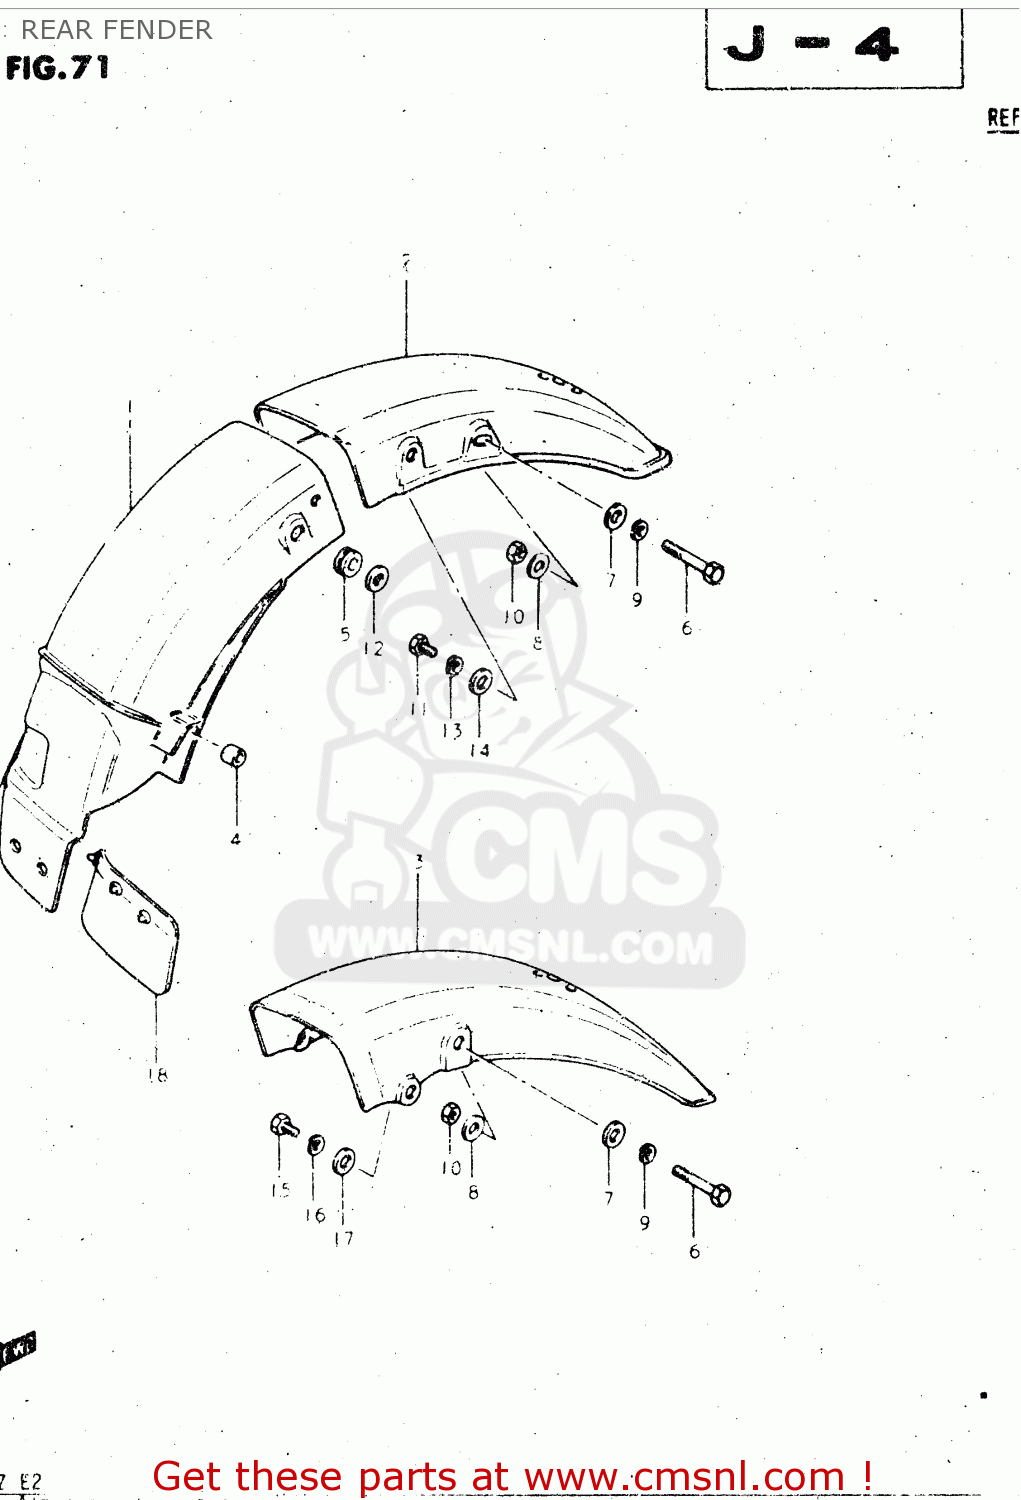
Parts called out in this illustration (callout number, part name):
1	FENDER,REAR
2	BODY, REAR FENDER REAR
3	BODY, REAR FENDER REAR
4	CUSHION
5	CUSHION
6	BOLT
7	WASHER
8	WASHER
9	LOCK WASHER
10	NUT
11	BOLT 8X12
12	WASHER
13	LOCK WASHER
14	WASHER
15	BOLT
16	LOCK WASHER
17	WASHER
18	GUIDE,RR FENDER MUD
